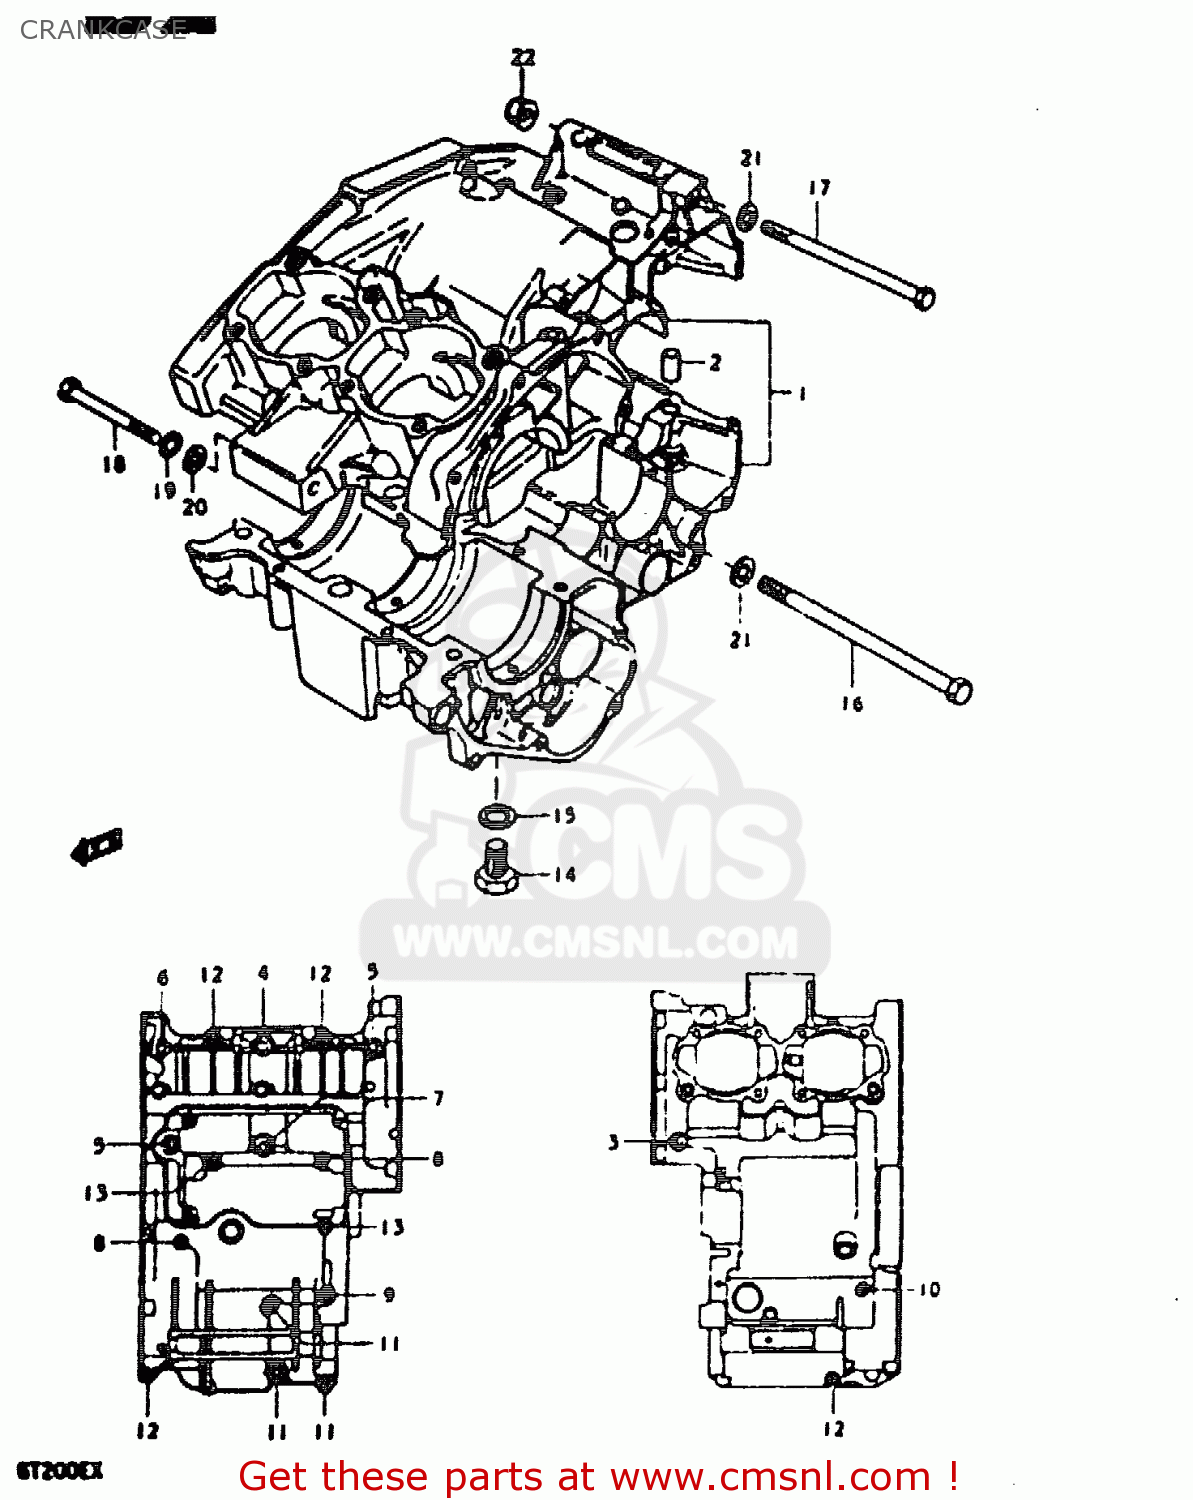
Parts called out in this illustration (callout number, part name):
1	CRANKCASE SET
2	PIN
3	BOLT
4	BOLT 8X75
5	BOLT 8X65
6	BOLT 8X55
7	BOLT
8	BOLT (6X90)
9	BOLT (6X80)
10	BOLT 6X65
11	BOLT (6X60)
12	BOLT ,6X50
13	BOLT
14	PLUG
15	GASKET(14X19.2X2) (NAS)
16	BOLT
17	BOLT
18	BOLT,8X75
19	WASHER,LOCK,8.
20	WASHER
21	WASHER
22	NUT
